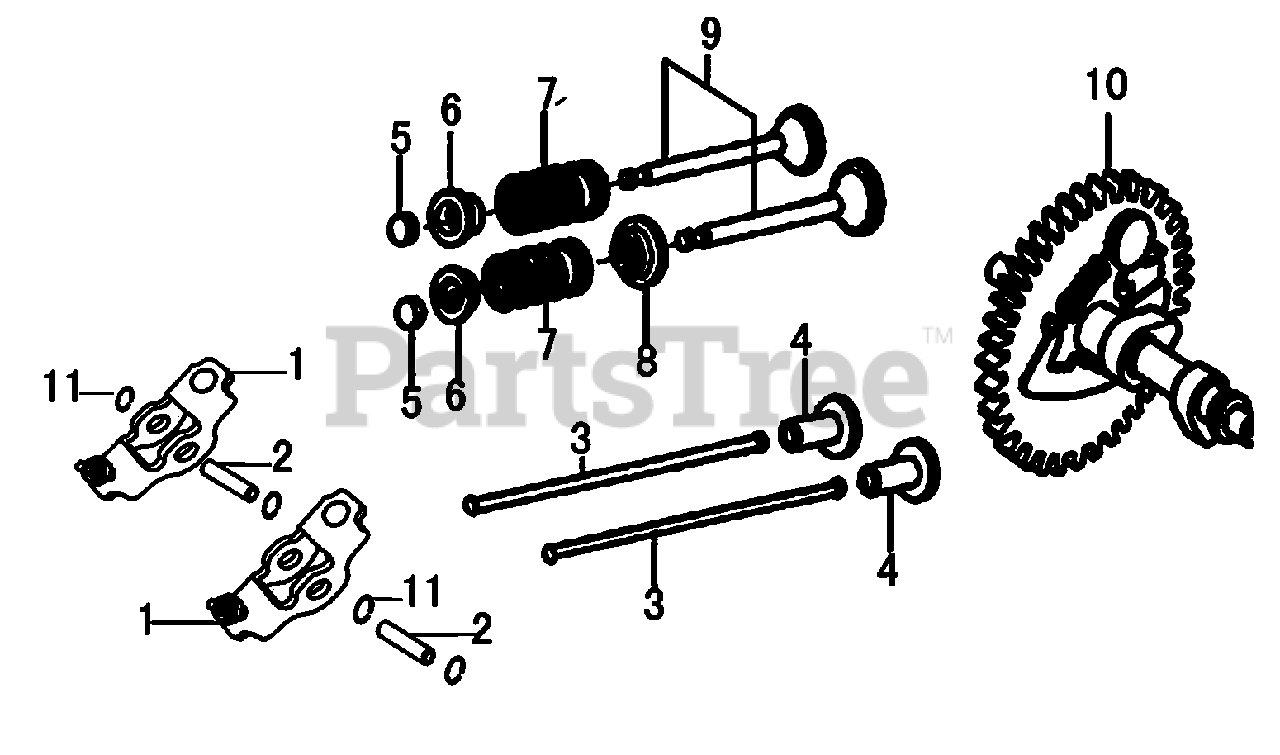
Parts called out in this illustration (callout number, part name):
1	ROCKER ARM
2	VALVE ROCKER SHAFT
3	ROD, PUSH
4	LIFTER VALVE
5	ROTATOR, VALVE
6	RETAINER, VALVE SPRING
7	SPRING, VALVE
8	SEAL, GUIDE
9	VALVE SET
10	CAMSHAFT ASSY
11	SPLIT WASHER
